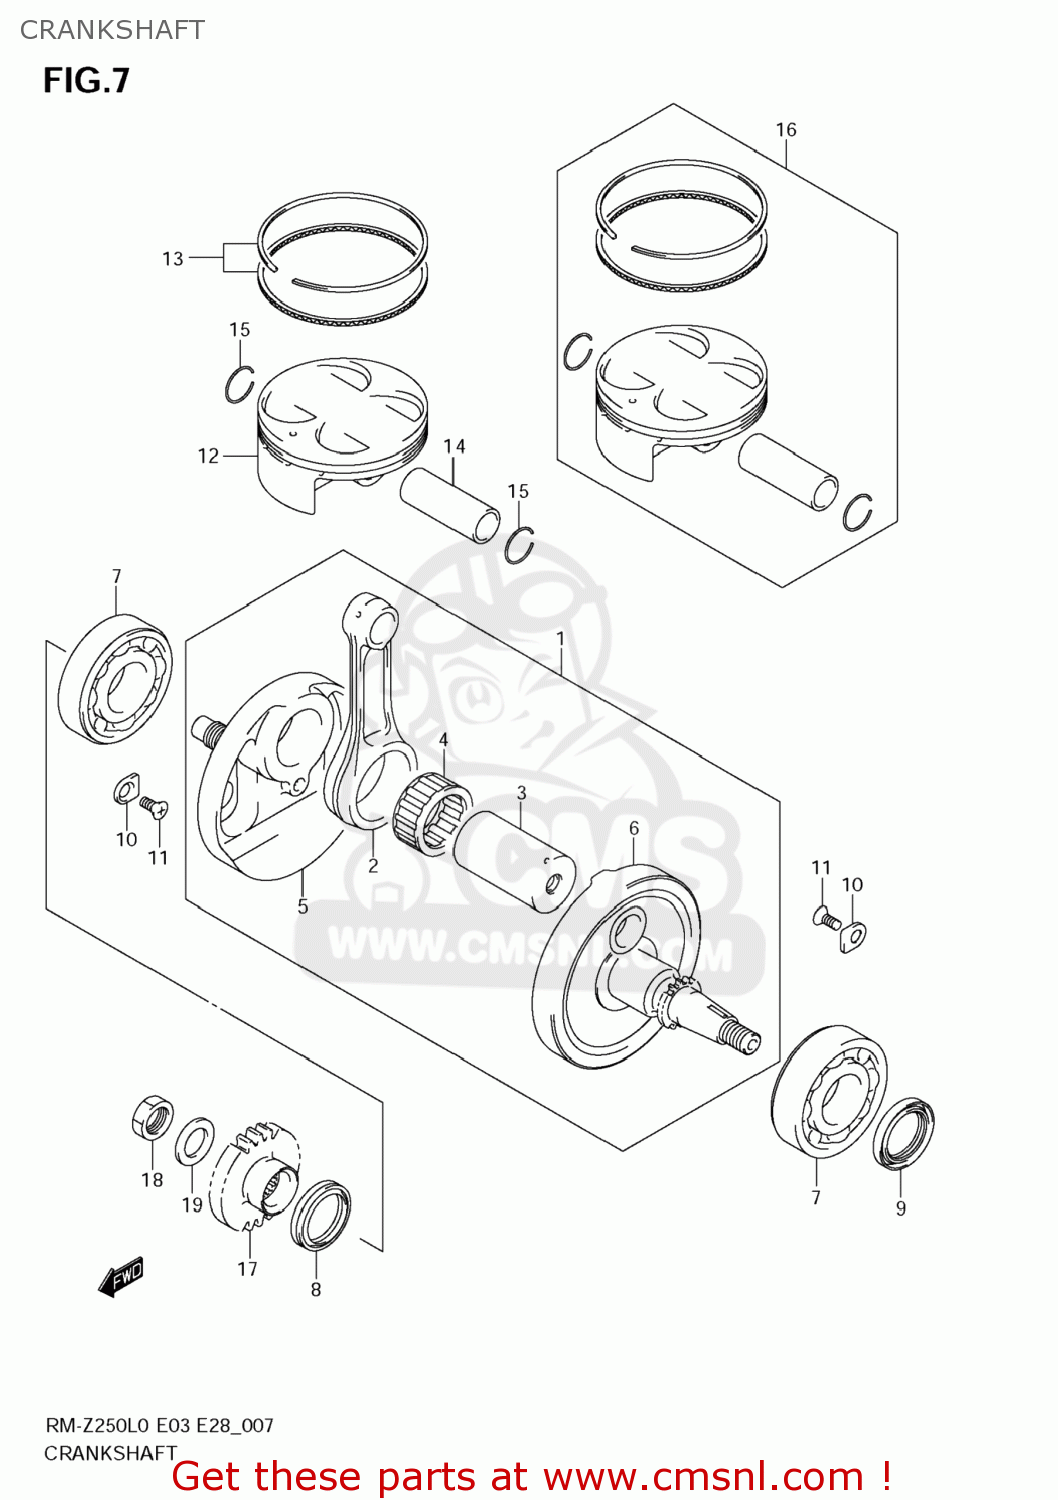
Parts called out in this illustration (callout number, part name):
1	CRANKSHAFT ASS
2	CONNECTING ROD
3	PIN,CRANK
4	BEARING(30X38X18)
5	CRANKSHAFT,R
6	CRANKSHAFT,L
7	BEARING(30X63X16)
8	SEAL,OIL(30X40X7)
9	SEAL,OIL(30X40X6)
10	RETAINER,CRANKSHAFT BEARING
11	SCREW(6X12)
12	PISTON
13	RING SET,PISTON
14	PIN,PISTON
15	RING,SNAP 16MM
16	PISTON KIT
17	GEAR,PRIMARY DRIVE
18	NUT
19	WASHER
